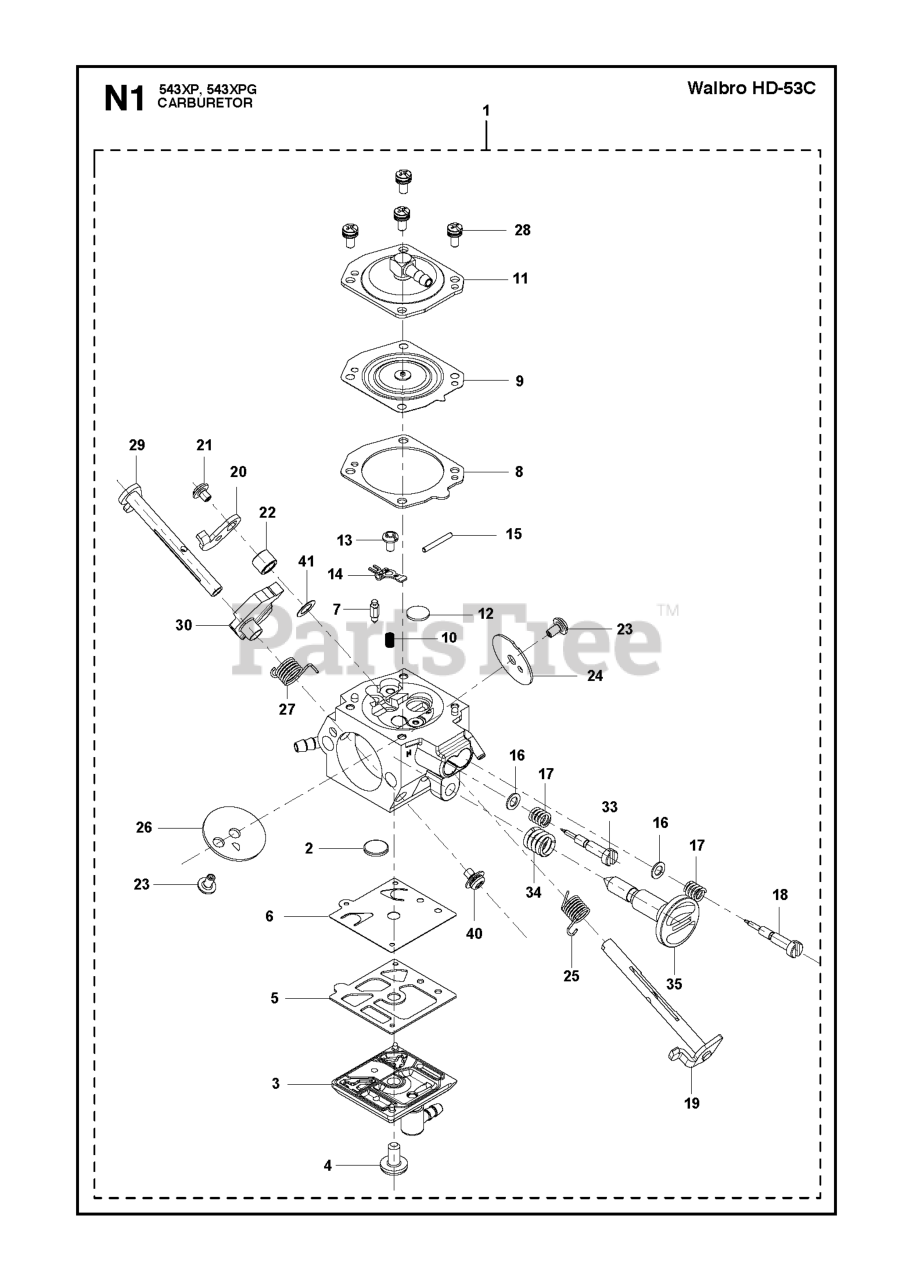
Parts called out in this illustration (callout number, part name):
1	CARBURETTOR
2	SCREEN
3	COVER ASSEMBLY PUMP 21-3780
4	SCREW Z149181130
6	95-75 DIAPHRAGM Z335081260
7	VALVE INLET
9	DIAPHRAGM ASSEMBLY METERING 95
11	COVER PUMP
18	NEEDLE IDLE
19	SHAFT ASSY THROTTLE 22-4282
20	LEVER THROTTLE 18-3551
22	SPACER THROTTLE LEVER 148-96
23	SCREW 96-3240
24	VALVE THROTTLE 34-314
25	SPRING 98-3706
26	VALVE CHOKE 34-3504
27	SPRING 98-3718
28	SCREW ASSY
29	SHAFT ASSY CHOKE 22-4356
30	LEVER FAST IDEL 18-3566
33	NEEDLE HIGH SPEED
34	SPRING 98-3706
